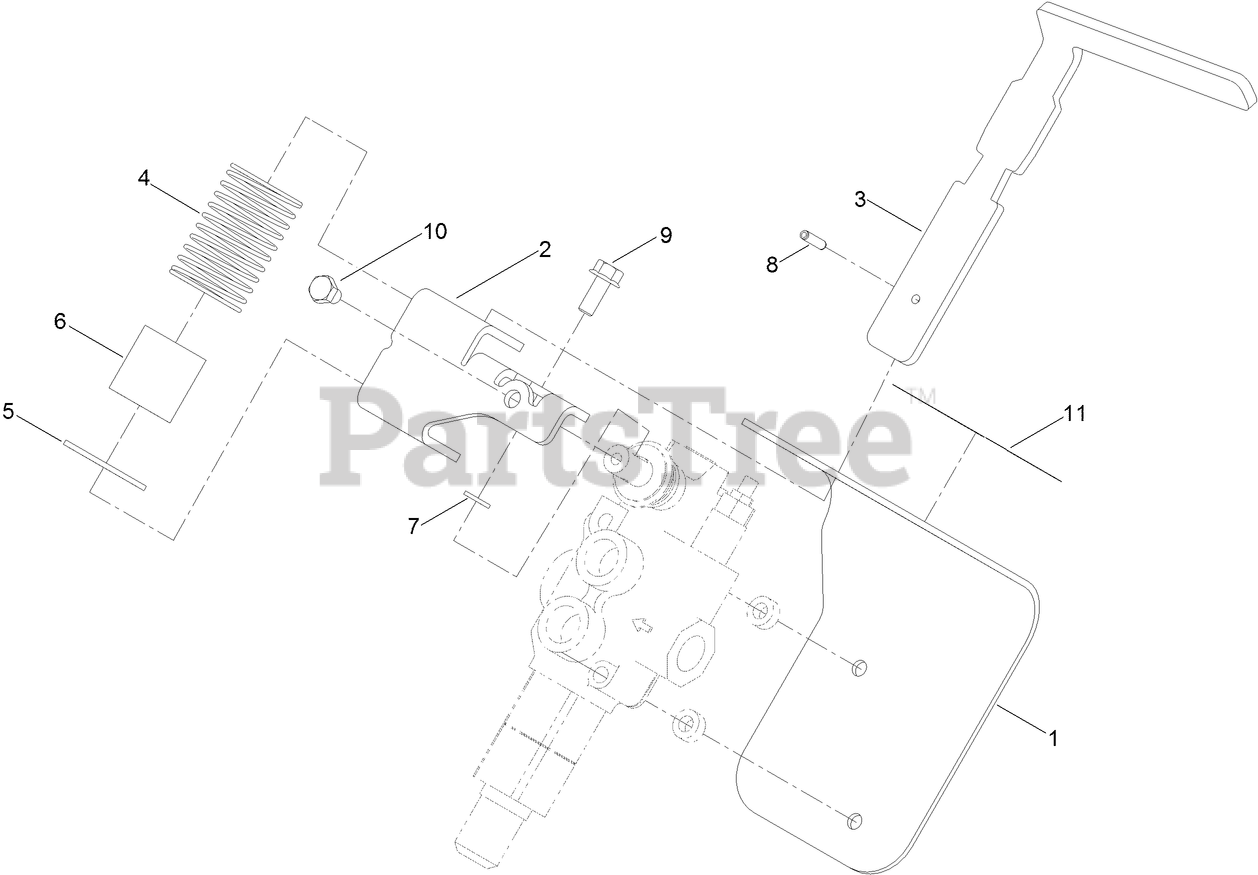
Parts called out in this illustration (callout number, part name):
1	BRACKET-AUXILIARY
2	MOUNT-LEVER, AUXILIARY
3	HANDLE-LEVER, AUX
4	SPRING
5	RETAINER-SPRING, AUXILIARY
6	TUBE-SPRING
7	WASHER-LOCK
8	PIN-SPRING
9	SCREW-HHF
10	SCREW-HH
11	DECAL-AUXILIARY, CE
